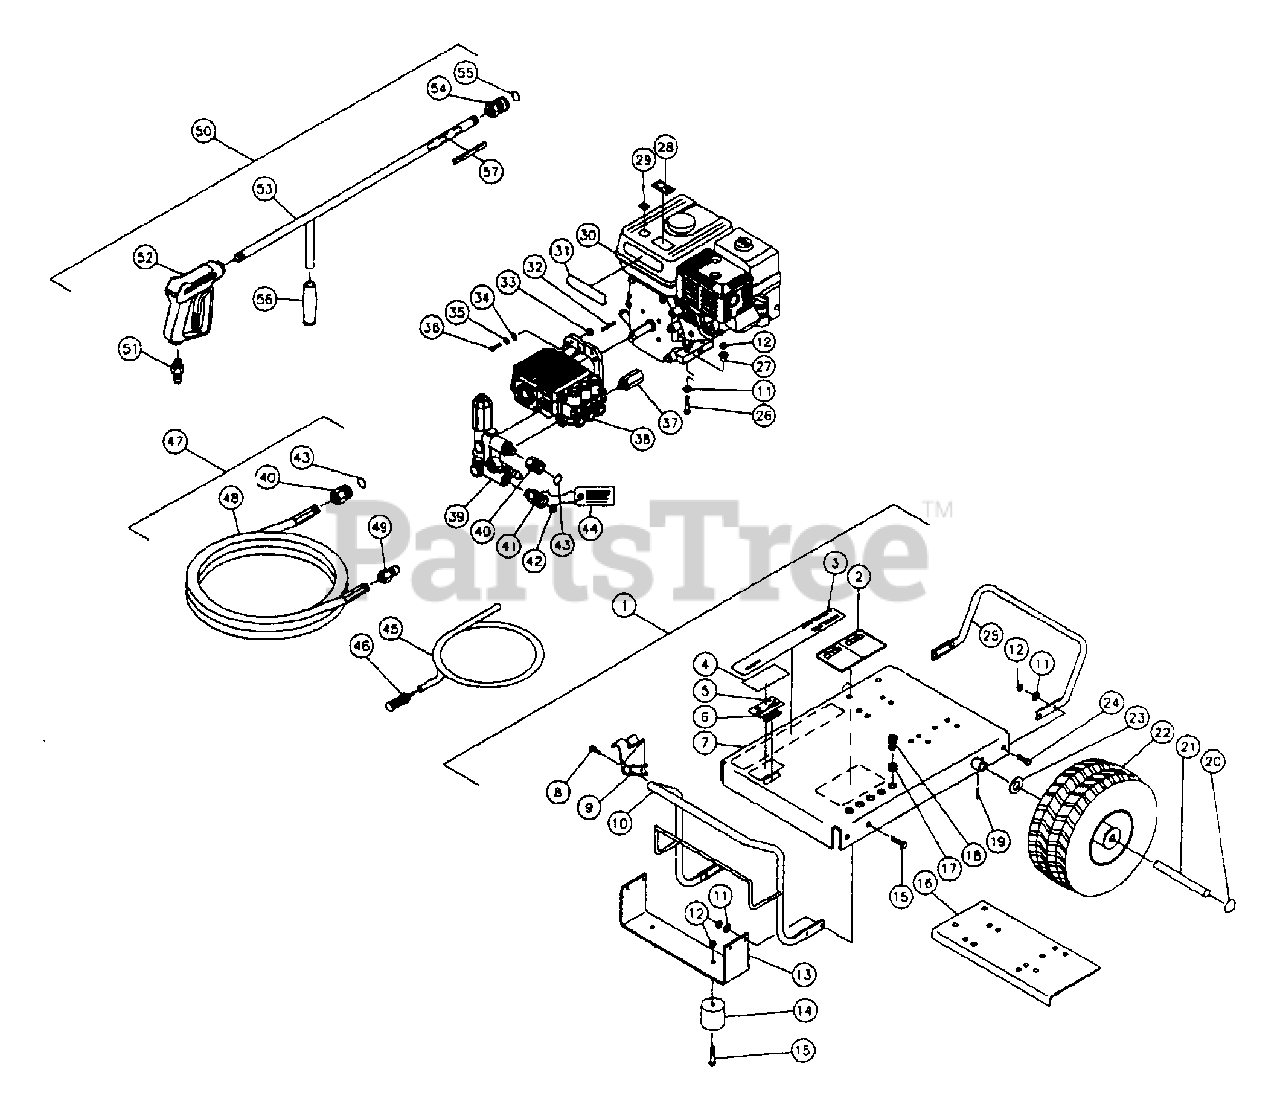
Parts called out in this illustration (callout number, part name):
1	Base Plate Assly
2	Decal-Caution/Warning Statements
3	Decal-CPW2800
4	Decal-Clear Laminate
5	Decal-Silver Sticker I.D.
6	Decal-Serial Number
7	Base Plate
9	Wand Holder
10	Handle-Front
13	Underbracket
14	Isolator
16	Support Bracket
18	Spray Nozzle for 0004
19	Roll Pin
25	Handle-Rear
27	Shim-Engine
28	Decal-Warning: Muffler Hot
29	Decal-Caution: Engine Cool
30	Engine-9.0 HP Honda
31	Operating Instructions
33	Shim-Pump
35	Lockwasher
37	Heat Dump Valve
39	Unloader
40	Quick Connect socket-3/8
41	Garden Hose Swivel
42	Inlet Screen
44	Tag-Water Supply Inlet
45	Detergent Hose-1/4
46	Detergent Strainer
47	High Pressure Hose Assembly
48	High Pressure Hose
49	Quick connect Plug-3/8"
50	Gun-Wand Assembly
51	Quick connect Plug-3/8
52	Gun Assembly
53	Wand with Handle
54	Quick Connect Socket-1/4"
56	Handle Grip
57	Decal-Warning: Risk of Injection
